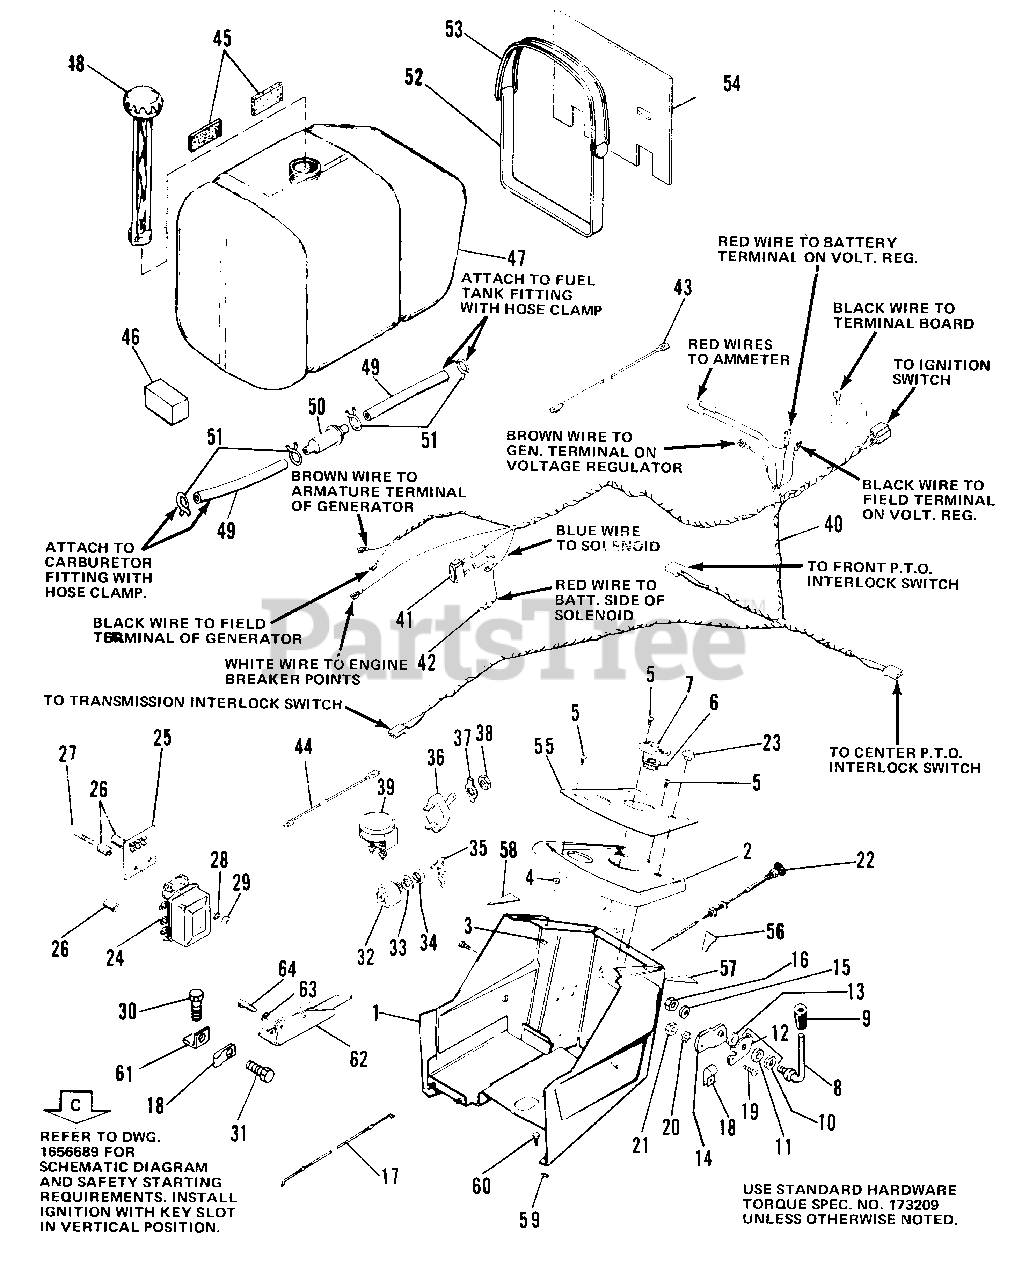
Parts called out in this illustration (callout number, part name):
1	DASH ASSEMBLY
2	PANEL, Instrument
3	NUT, Retainer, Tinn.
4	WASHER, Plain, 3/16
5	SCREW, Mach. Rd. Hd., 1/4-20 x 1/2
7	PLATE STEERING, Adj.
8	HANDLE, Clutch Control
9	KNOB, Tapered
12	STOP, Throttle Kit (inc. ref. 10, 11)
14	ARM, Throttle
15	LOCKWASHER, Dished Shakeproof, 3/8
16	LOCKNUT, Hex, 3/8-16
17	CONTROL, Throttle
18	CLIP, Bowden Wire
19	SCREW, Rd. Hd., No. 10-32 x 1/2
20	LOCKWASHER, External, No.10
21	NUT Mach. Hex, No. 10-32
22	CONTROL, Choke
23	PLUG, Button
24	REGULATOR, Voltage
25	BOARD, Terminal
27	CAPSCREW, Hex Hd., 1/4-20 x 1-3/4
28	LOCKWASHER, Shakerproof, 1/4
29	NUT, Hex, 1/4-20
30	SCREW, Hex Hd., 1/4-20 x 5/8
31	SCREW, Taptite No. 10-24 x 1/2
32	SWITCH, Ignition
33	LOCKWASHER, Internal, 5/8
34	NUT, Hex Special
35	KEY & RING ASSEMBLY
36	SWITCH, Toggle
37	PLATE
38	NUT
40	HARNESS ASSEMBLY
41	CIRCUIT BREAKER
42	WIRE ASSEMBLY
43	WIRE ASSEMBLY
44	WIRE ASSEMBLY, Light Switch
45	GASKET, Felt
46	PAD, Fuel Tank
47	TANK, Fuel
48	CAP, Fuel Tank
50	FILTER, Fuel
51	CLAMP, Hose
52	STRAP, Tank
53	STRAP, Fuel Tank
54	INSULATION, Fuel Tank
55	DECAL, Instrument Panel
56	DECAL, Ignition
57	DECAL, Throttle Control
58	DECAL, Hydrostatic Control
59	NUT, Speed, Tinn.
60	SCREW, Hex Hd. Thd. Forming, No. 14 x 3/4
61	BRACKET, Cable
62	QUADRANT
63	LOCKWASHER, External Tooth, 5/16
64	SCREW, Special
